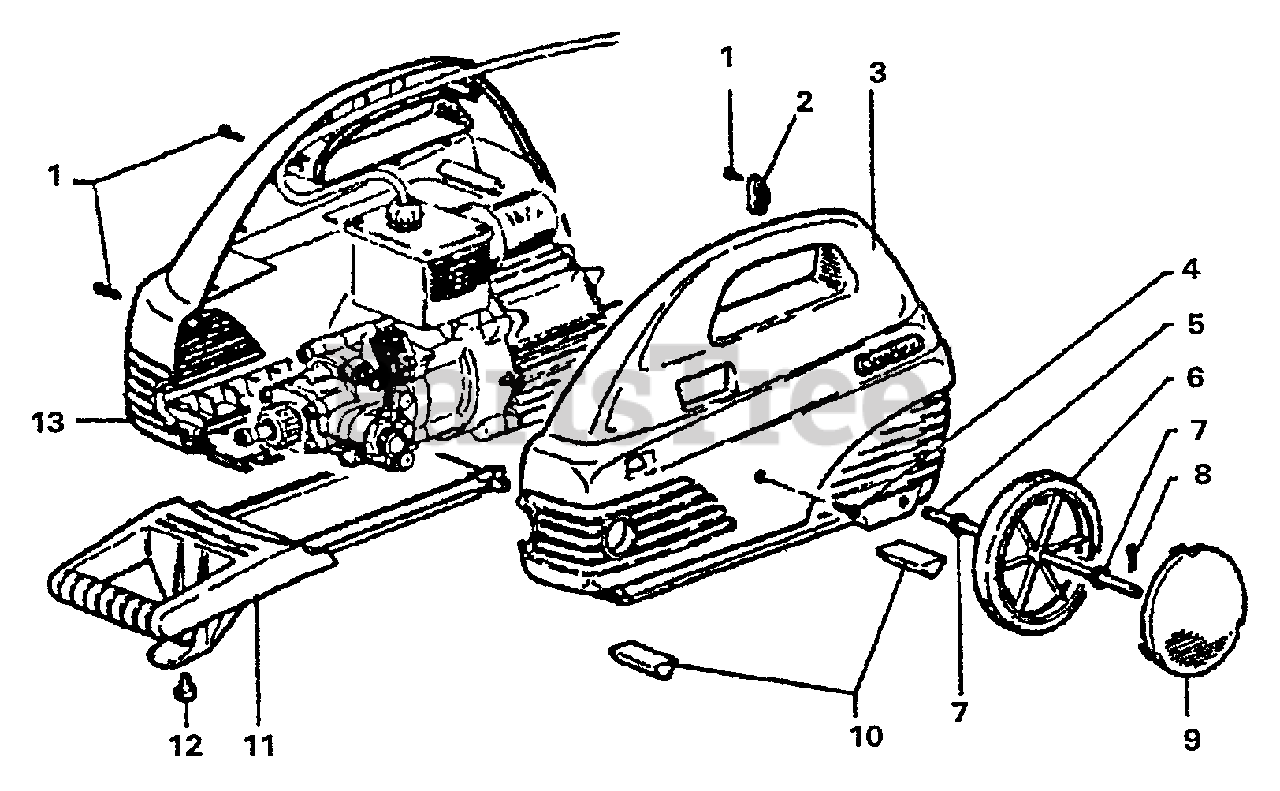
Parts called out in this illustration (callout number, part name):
1	SCREW M4×18
2	COVER
3	COVER, LEFT
4	SCREW - 4×13
5	SHAFT
7	WASHER
8	PIN, COTTER
9	CAP, WHEEL
10	FEET, PUMP
11	HANDLE
12	PLUG
13	COVER, RIGHT
